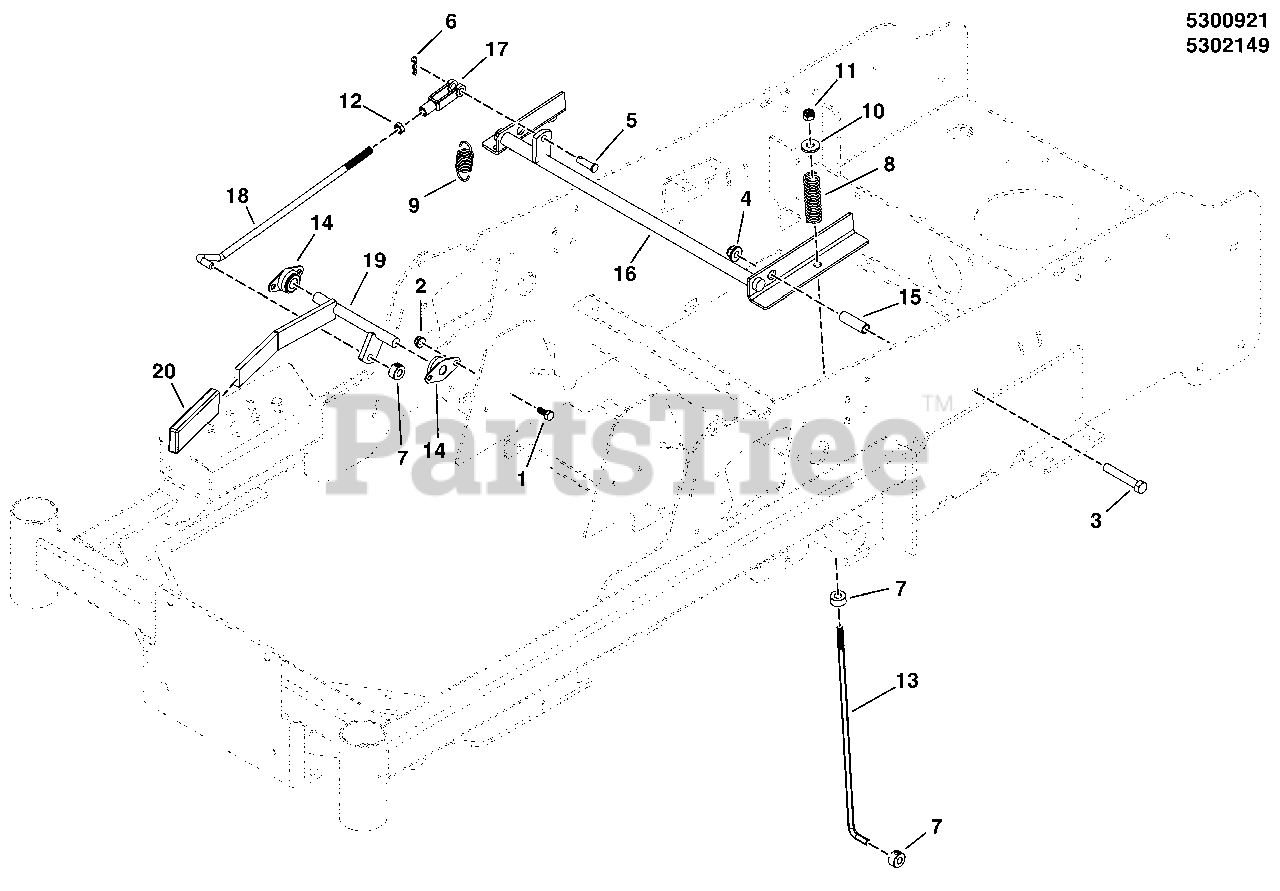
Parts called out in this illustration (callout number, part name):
1	HHCS, 1/4-20 X 0.625, GR5, ZINC/CLEAR
2	NUT, 1/4-20 Hex Nylock Flange
3	BOLT, 3/8-16 X 2-1/4" GD5 CZ
4	NUT, 3/8 - 16 HEX NYLOCK FLANGE
5	PIN, CLEVIS, 5/16 X 1, PLATED
6	PIN, HAIR, .0585 X 1-1/8, 1/4 EYE, YZ
7	COLLAR, 5/16" Set
8	SPRING-COMP, .594ID X 2.68LG X .080WR
9	SPRING-EXT, .740 ODX2.025LGX.072WR, BLK
10	WASHER, 5/16" USS
11	NUT, Hex, Nylon Lock, 5/16-24
12	NUT, Hex Jam, 5/16-24
13	ROD, BRAKE CTRL, LOWER - CONZ
14	BEARING, 1/2 FLANGED, PLASTIC BALL
15	SPACER, .38 x .50 x 1.56
16	WELD, BRAKE SHAFT - BLK
17	CLEVIS, 5/16-24, STEEL, CLEAR ZINC
18	ROD, PULLER ROD
19	WELD, BRAKE SHAFT, HANDLE - BLK
19	WELD, BRAKE SHAFT, HANDLE - RED
20	GRIP, FOAM, 1/4 X 1 X 4.1
